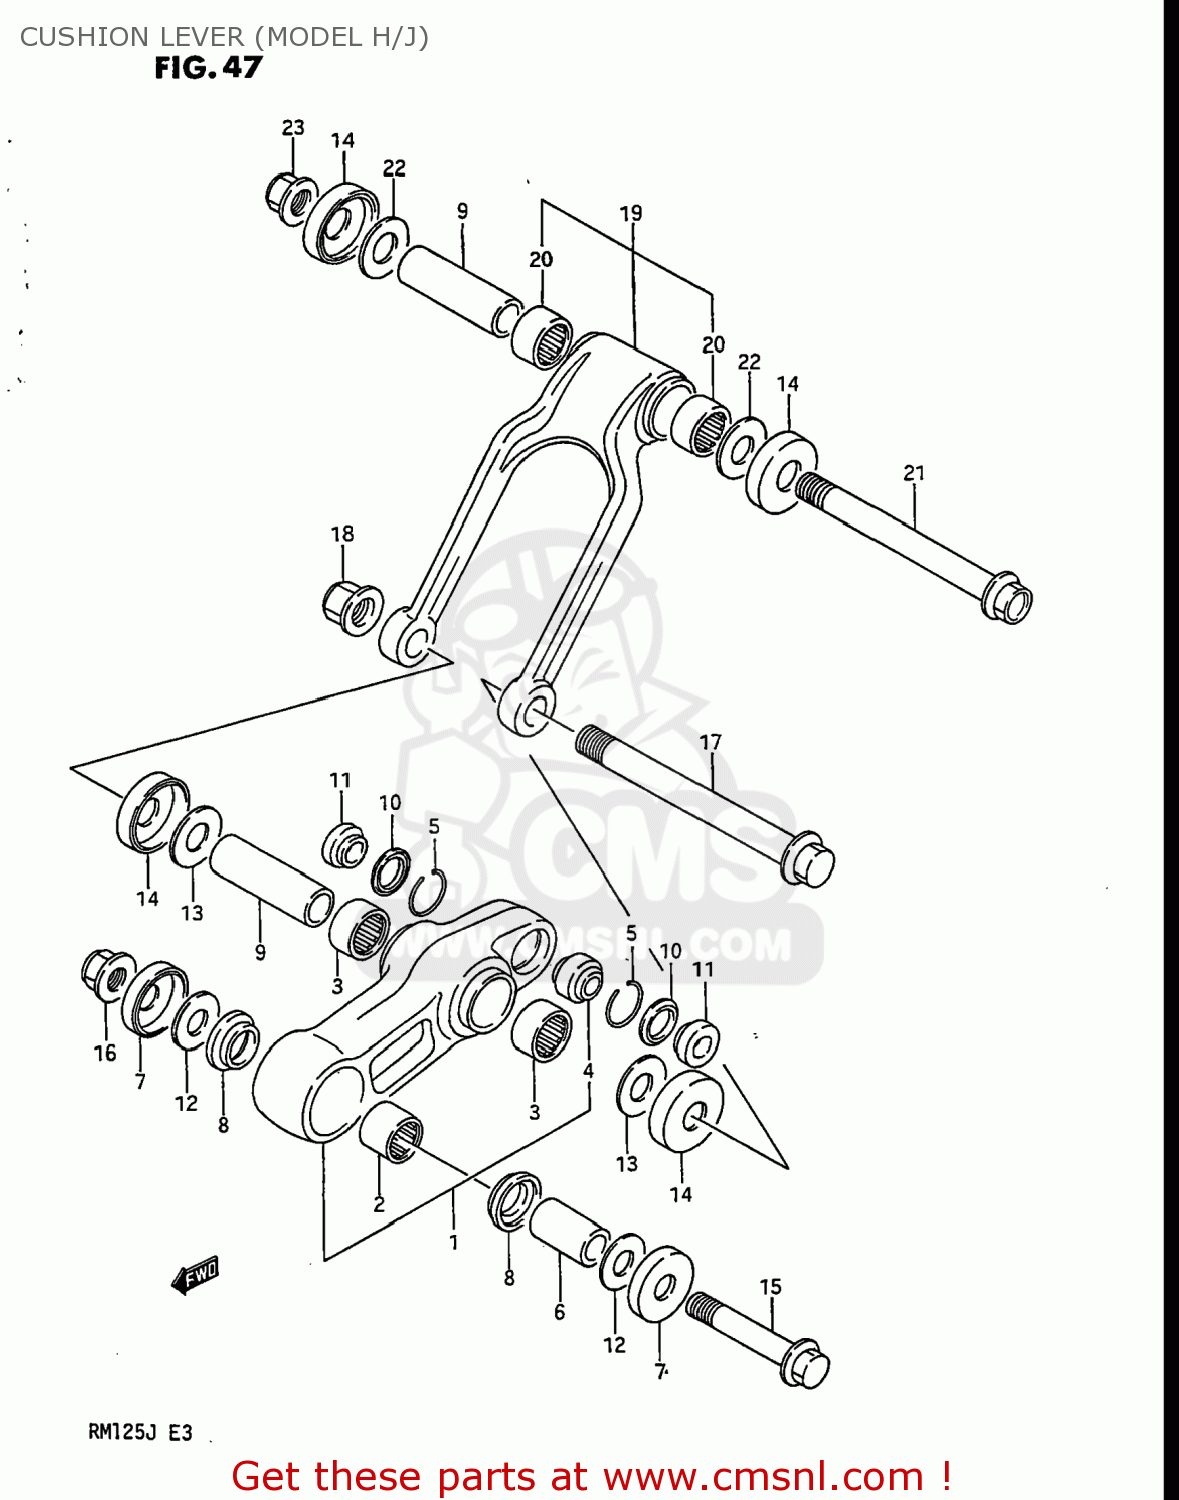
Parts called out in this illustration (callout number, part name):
1	LEVER SET,REAR CUSHION
2	BEARING(20X27X25)
3	BEARING(20X27X20)
4	BEARING,RR CUSHION LEVER
5	RING
6	SPACER,REAR CUSHION LEVER
7	COVER,REAR SWING ARM DUST
8	COLLAR,RR CUSHION LEVER FR
9	SPACER,REAR CUSHION LEVER
10	SEAL,DUST RR SHOCK ABSORBER
11	COLLAR
12	WASHER
13	WASHER
14	DUST SEAL,RR C
15	BOLT,RR CUSHION LEVER FR
16	NUT 12MM
17	SHAFT,RR CUSHION LEVER
18	NUT
19	LEVER SET,REAR CUSHION
20	BEARING(20X27X20)
21	BOLT,REAR CUSHION ROD
22	WASHER
23	NUT
